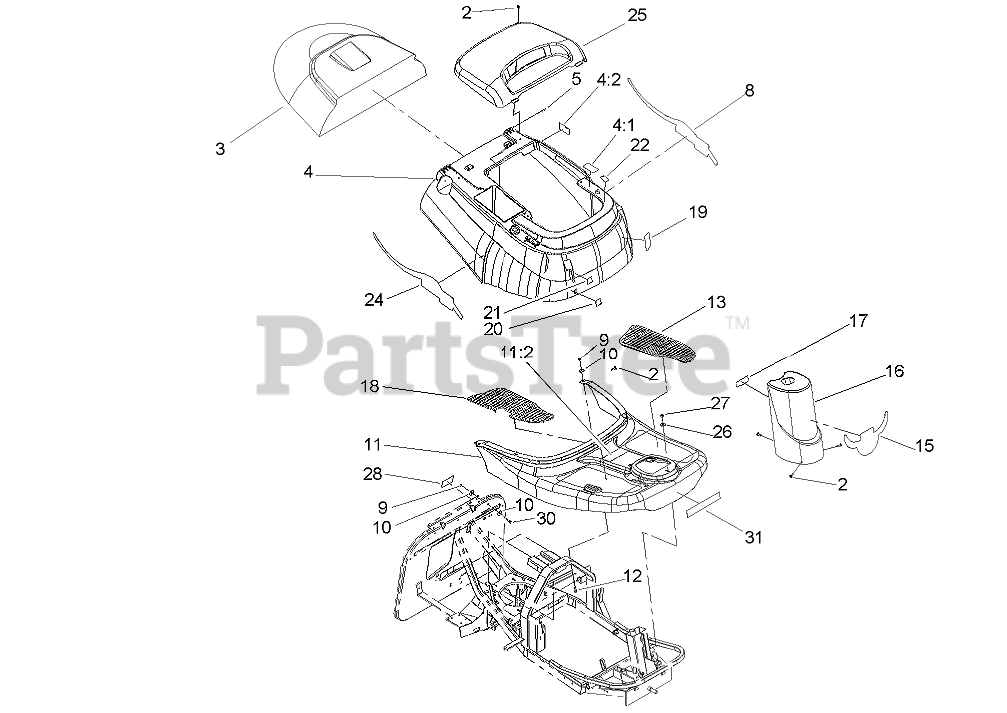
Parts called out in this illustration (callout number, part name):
2	Screw-HH, TAP
3	COVER-GRASS BAG
4	Shroud And Decal ASM
4:1	Decal-Danger
4:2	Decal-Warning, Hot
5	Pin-Dowel
8	DECAL-SIDE, LEFT
9	NUT-LOCK
10	Washer-Flat
11	FOOT REST AND DECAL ASM
11:2	Decal-Caution
12	SCREW-HH
13	Floormat-LH
15	DECAL-FRONT
16	Steering-Turret
17	Decal-Run Lights
18	Floormat-RH
19	Decal-HOC
20	Decal-PTO, Disengage
21	Decal-PTO, Engage
22	Decal-Switch
24	DECAL-SIDE, RIGHT
25	Cover-Engine
26	Washer-Flat
27	NUT-LOCK
28	Decal-Disengagement
30	SCREW-HH
